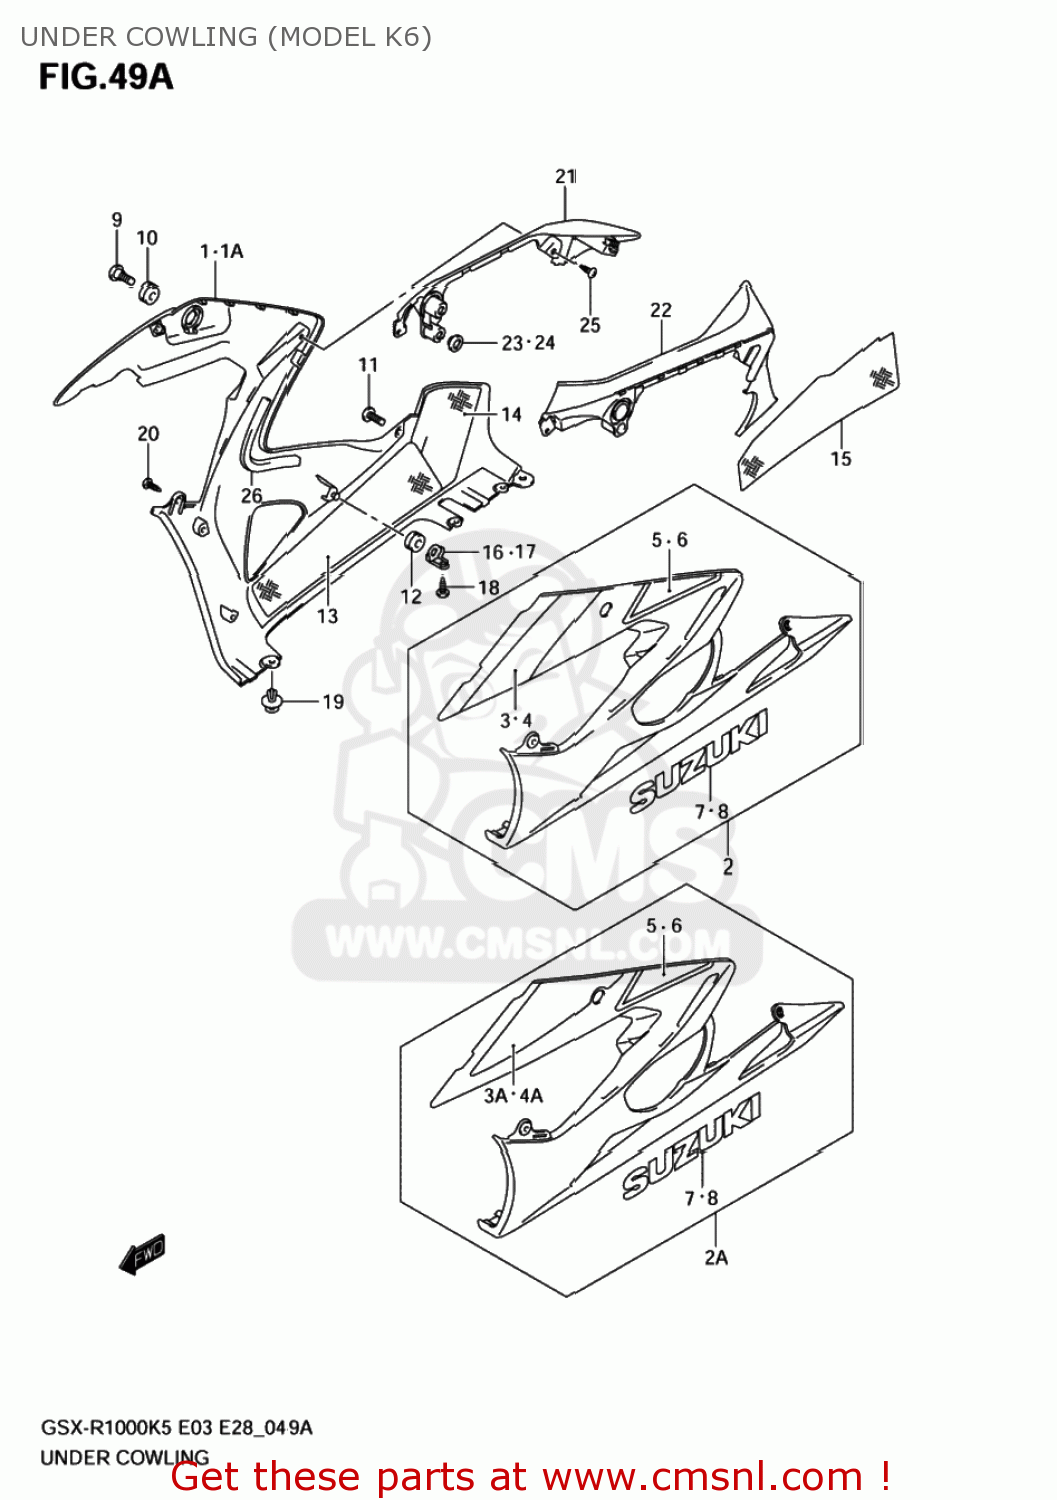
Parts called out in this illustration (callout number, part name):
1	COWLING,UNDER,R
1A	COWLING,UNDER,R
2	COWL,UNDER,L
2A	COWL,UNDER,L
3	TAPE,UNDER UPR,R
3A	TAPE,UNDER UPR,R
4	TAPE,UNDER UPR,L
4A	TAPE,UNDER UPR,L
5	TAPE,UNDER MIDDLE,R
6	TAPE,UNDER MIDDLE,L
7	EMBLEM,SUZUKI,R
8	EMBLEM,SUZUKI,L
9	SCREW(6X20)
10	CUSHION
11	SCREW(5X13)
12	CUSHION
13	SHIELD,HEAT UNDER NO.1,R
14	SHIELD,HEAT UNDER NO.2,R
15	SHIELD,HEAT UNDER,L
16	BRACKET,UNDER COWLING LWR,R
17	BRACKET,UNDER
18	BOLT
19	CLIP
20	SCREW
21	COVER
22	COVER
23	CUSHION
24	CUSHION
25	SCREW
26	CUSHION,UNDER COWLING,R
